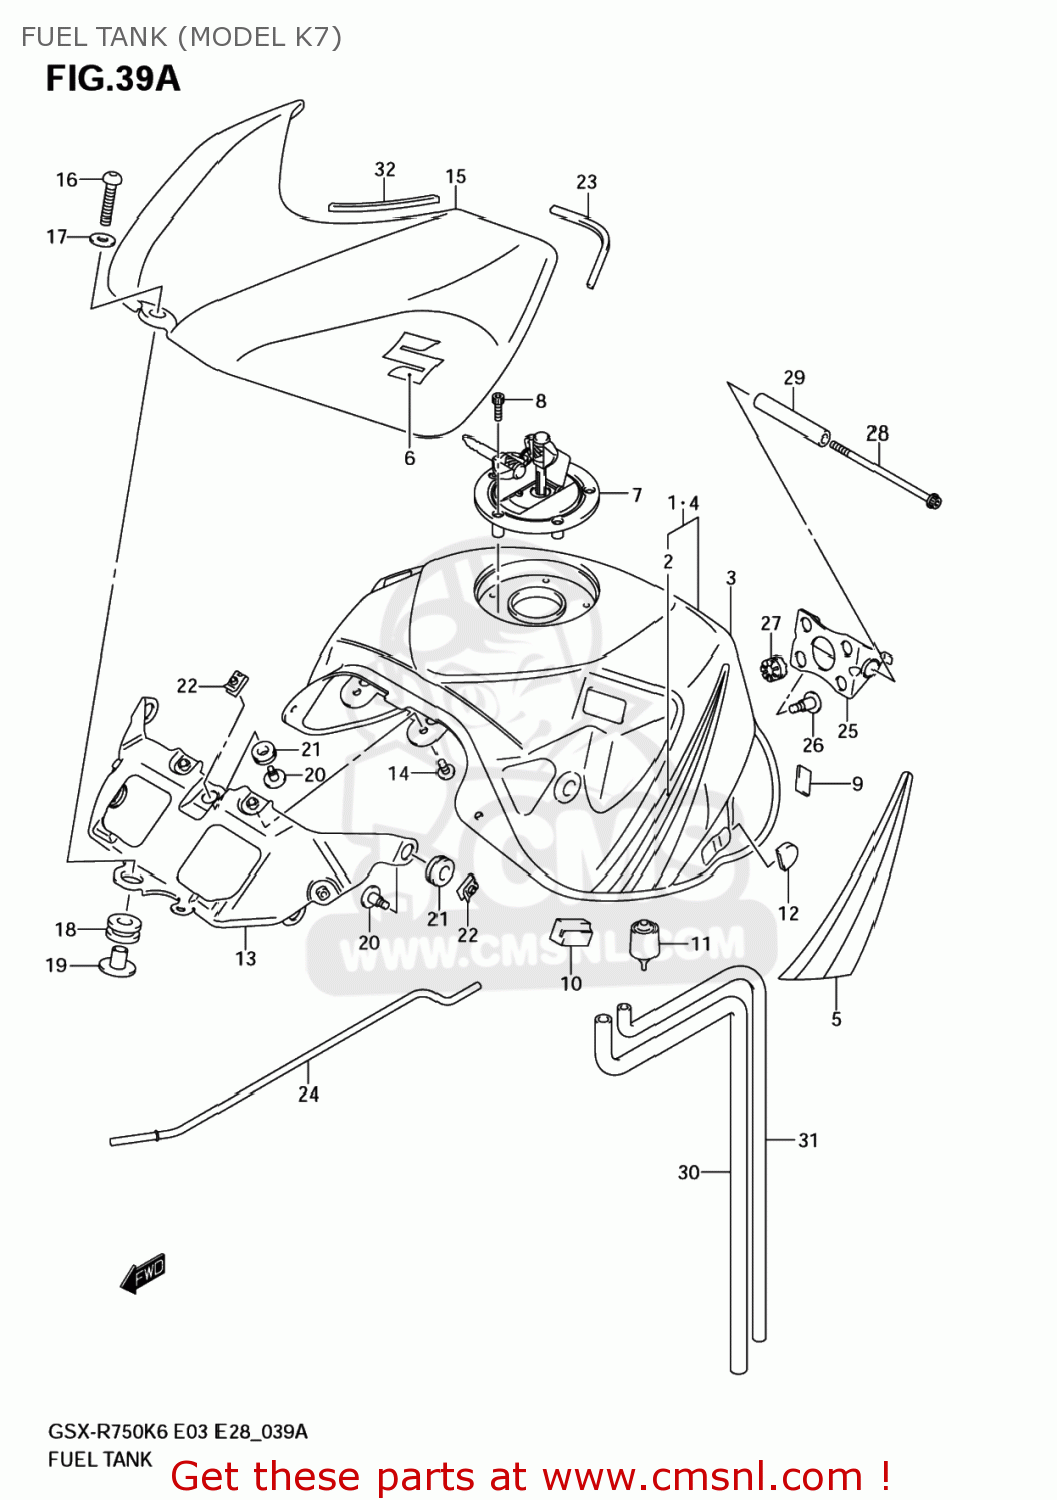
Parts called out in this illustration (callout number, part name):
1	TANK ASSY,FUEL(GRAY)
2	TAPE SET,FUEL TANK
3	TANK ASSY,FUEL(BLACK)
4	TANK ASSY,FUEL(BLUE)
5	TAPE SET,FUEL TANK
6	EMBLEM,S
7	CAP SET,FUEL TANK
8	BOLT(5X20)
9	FASTENER
10	CUSHION,FUEL TANK SIDE
11	CUSHION,FUEL TANK RR
12	CUSHION
13	BRACKET,FUEL TANK FR
14	SCREW(6X10)
15	COVER,FUEL TANK FR
16	BOLT(8X37)
17	WASHER(8.5X20X1.6)
18	CUSHION
19	SPACER (8.6X12
20	SCREW(5X16.4)
21	CUSHION
22	NUT
23	CUSHION,FUEL TANK COVER
24	STAY,FUEL TANK
25	BRACKET,FUEL TANK NO.1
26	SCREW,FUEL TAN
27	CUSHION
28	BOLT(6X110)
29	SPACER,FUEL TANK RR
30	HOSE,TANK WATER DRAIN
31	HOSE,TANK BREATHER
32	CUSHION,TANK COVER
